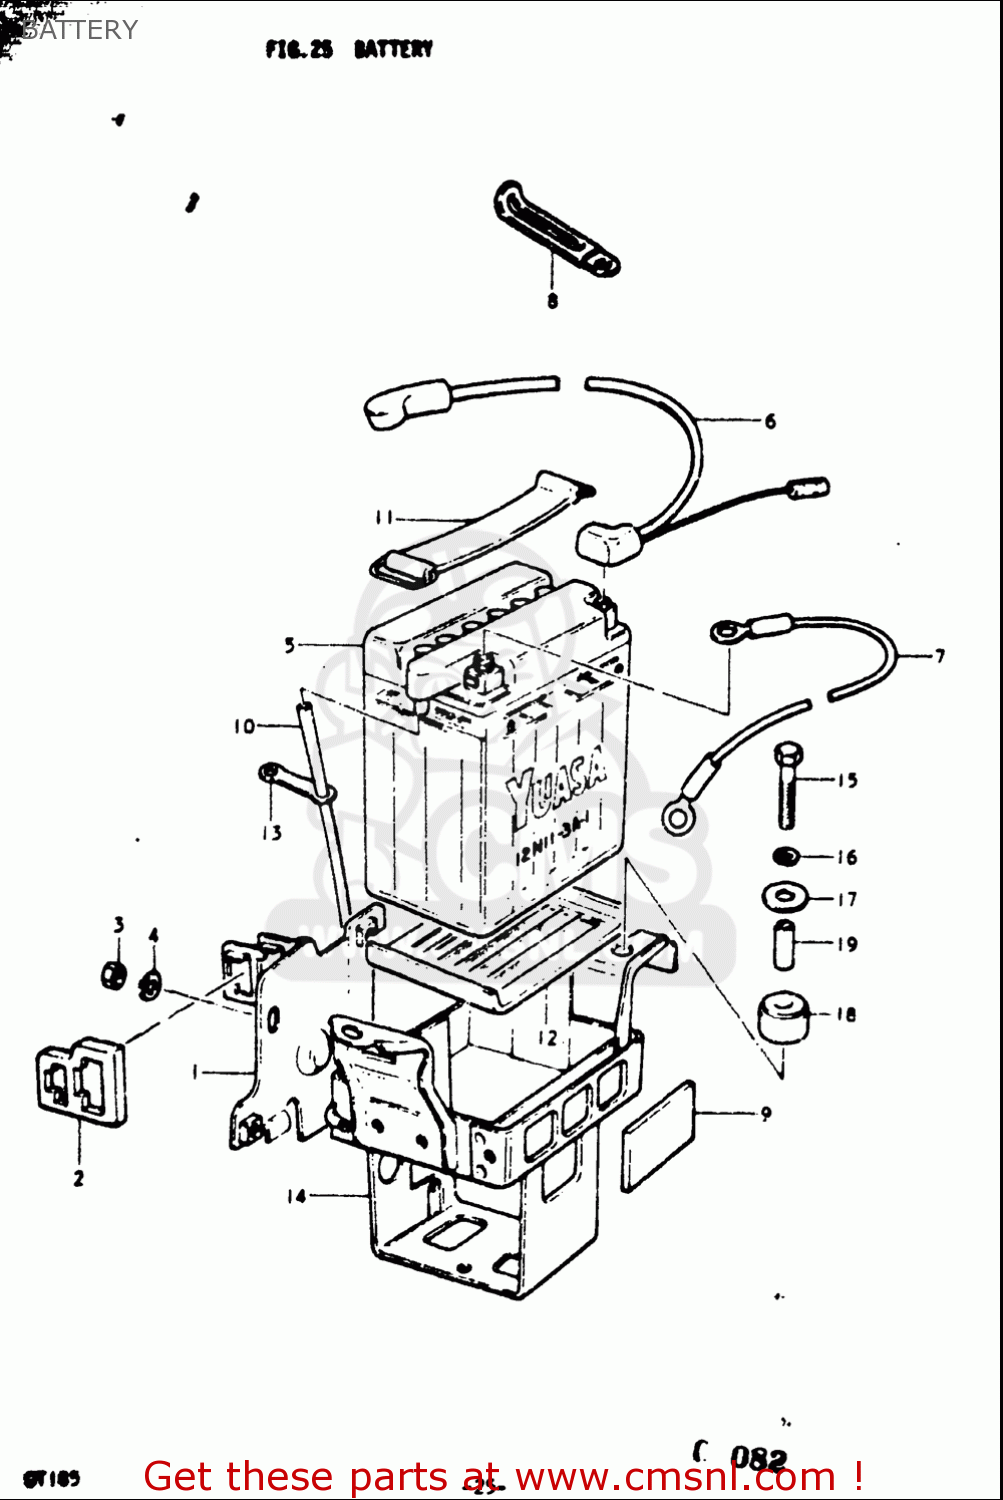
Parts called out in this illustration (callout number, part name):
3	NUT
4	WASHER,LOCK
5	BATTERY ASSEMBLY (12V)
8	CLAMP(L:65)
9	CUSHION(30X50X3)
10	HOSE,BATTERY EXHAUST(L:780)
11	BAND
13	CLAMP
15	BOLT
16	WASHER,LOCK
17	WASHER(6.5X18X1.6)
18	CUSHION
19	SPACER(6.1X8X15.5)
